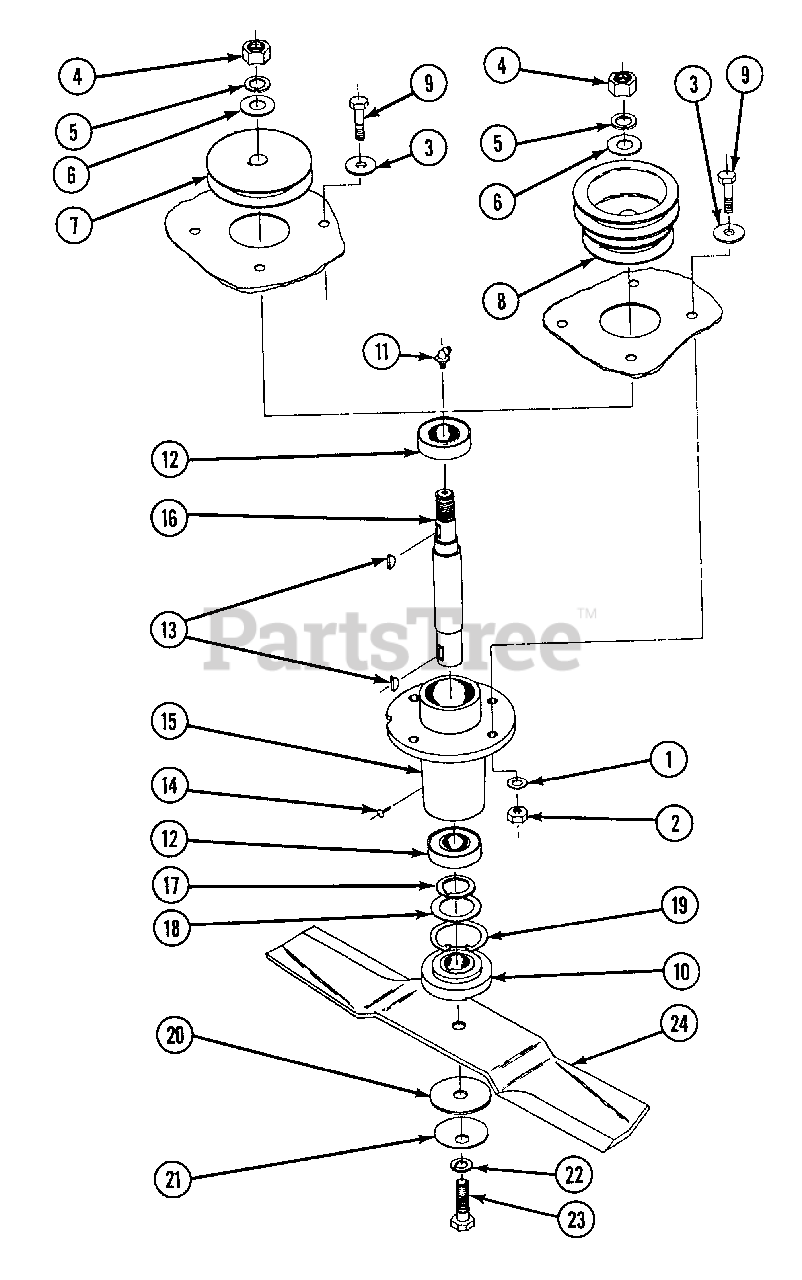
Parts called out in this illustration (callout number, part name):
1	LOCKWASHER, SPLT SPRNG: 3/8
2	LOCKNUT, M-F: 3/8-24NF
3	WASHER, REINFORCEMENT
4	NUT, HEX JAM: 3/4
5	LOCKWASHER, SPLT SPRNG: 3/4
6	FLAT WASHER, NARROW: 3/4
7	PULLEY, SINGLE GROOVE: 3/4 BORE 4" OD
8	PULLEY, 2 GROOVE: 3/4 BORE
9	CAPSCREW, HX HD: 3/8-24NF X 1-1/2
10	BLADE SPACER
11	GREASE FITTING
12	BEARING, 1"ID X 2" OD
13	KEY, WOODRUFF: 1/4 X 3/4
14	DRIVE SCREW: NO.4 X 3/16
15	DECK SPINDLE HOUSING
16	DECK SPINDLE SHAFT
17	ARBOR SPACER
18	SEAL WASHER
19	RETAINING RING
21	WASHER, CUPPED
22	LOCKWASHER, SPLT SPRNG: 1/2
23	CAPSCREW, HX HD: 1/2-13 X 1-1/2 GR 5
24	BLADE, LOW LIFT, 17" CUT (48" DECK)
